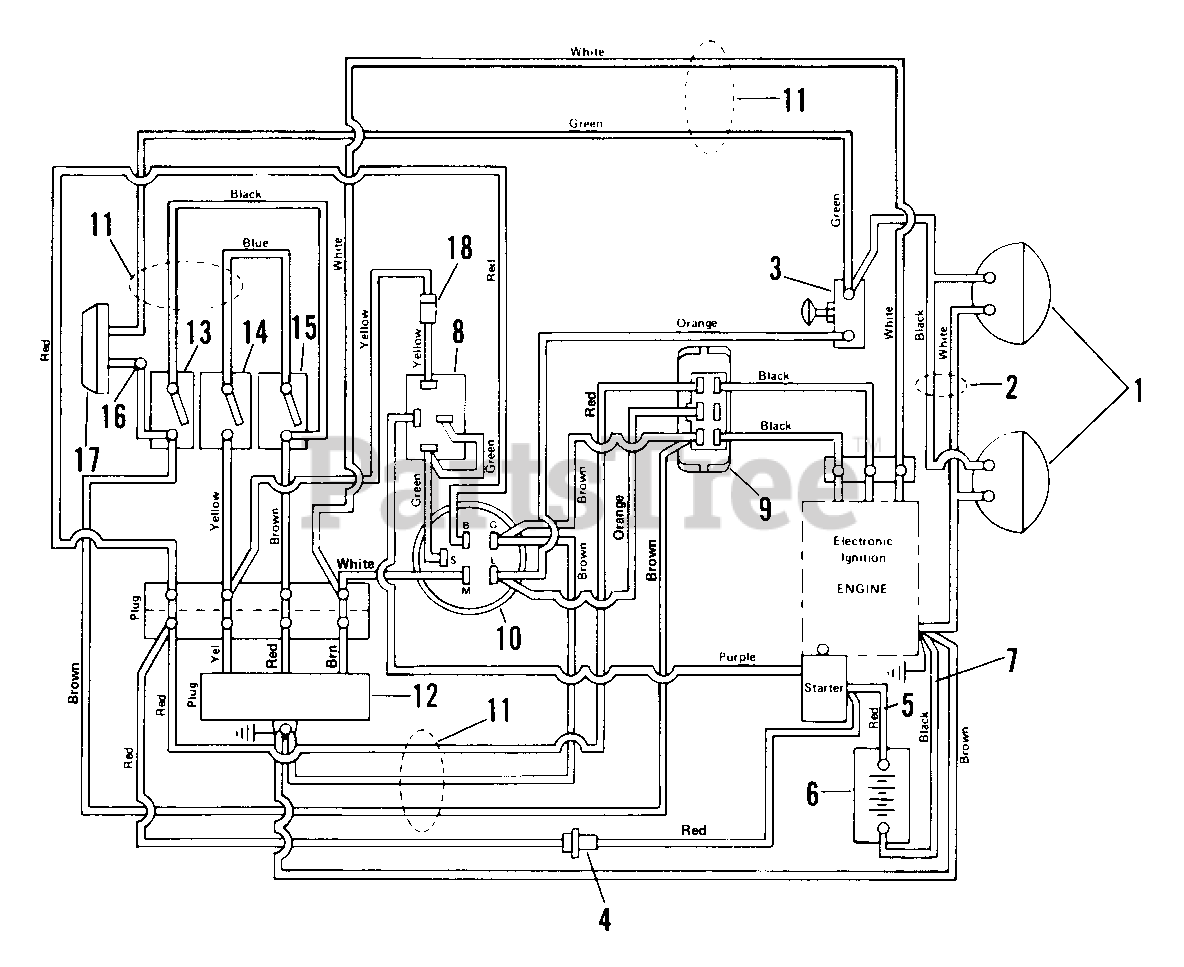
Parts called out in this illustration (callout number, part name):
1	HEAD LIGHT
2	WIRE HARNESS - HEADLIGHT
3	LIGHT SWITCH
6	BATTERY
7	CABLE-GROUND
8	RELAY
9	REGULATOR
10	IGNITION SWITCH ASSY- KAW/KOHL
11	WIRE HARNESS-KAWASAKI
12	MODULE
13	SWITCH SEAT
14	SWITCH INTERLOCK
15	SAFETY SWITCH
16	MALE DISCONNECT ADAPTER
17	TAIL LIGHT ASSEMBLY W/BULLET
18	MOLDED DIODE PLUG 1 AMP
